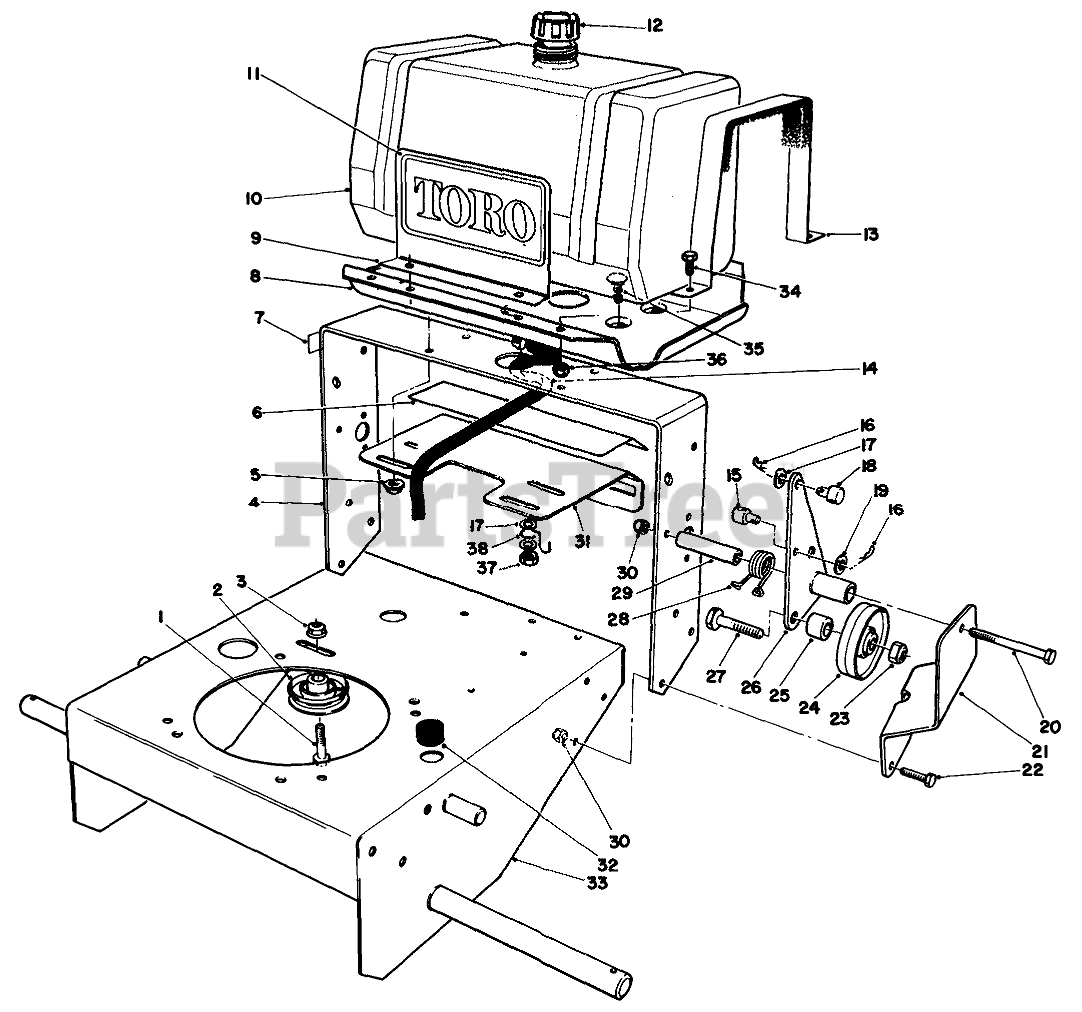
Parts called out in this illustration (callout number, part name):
1	SCREW-HH
2	PULLEY-IDLER
3	NUT-HF
4	Frame-Rear
5	NUT-HF
6	Decal-Ground Speed
7	Decal-Fuel Shut Off
8	PLATE-FUEL TANK
9	DECAL-PLATE
10	TANK-FUEL
11	DECAL
12	GAS CAP ASM
13	STRAP ASM
14	HOSE-FUEL
15	ROD FITTING
16	PIN-COTTER
17	WASHER-PLAIN
18	ROD FITTING
19	WASHER-PLAIN
20	SCREW-HH
21	Support-Idler L.H.
22	SCREW-HH
23	NUT-LOCK, NI
24	IdlerWheel
25	WHEEL IDLER SPACER
26	LH IDLER BRKT WA
27	SCREW-LEVELER
28	SPRING-TORSION, LH
29	PIVOT-IDLER SPACER
30	NUT-LOCK, NI
31	Plate
32	GROMMET
33	Frame
34	SCREW-HH
35	SCREW-CARR
36	NUT-LOCK, NI
37	NUT-LOCK, NI
38	GAS LINE CLIP
